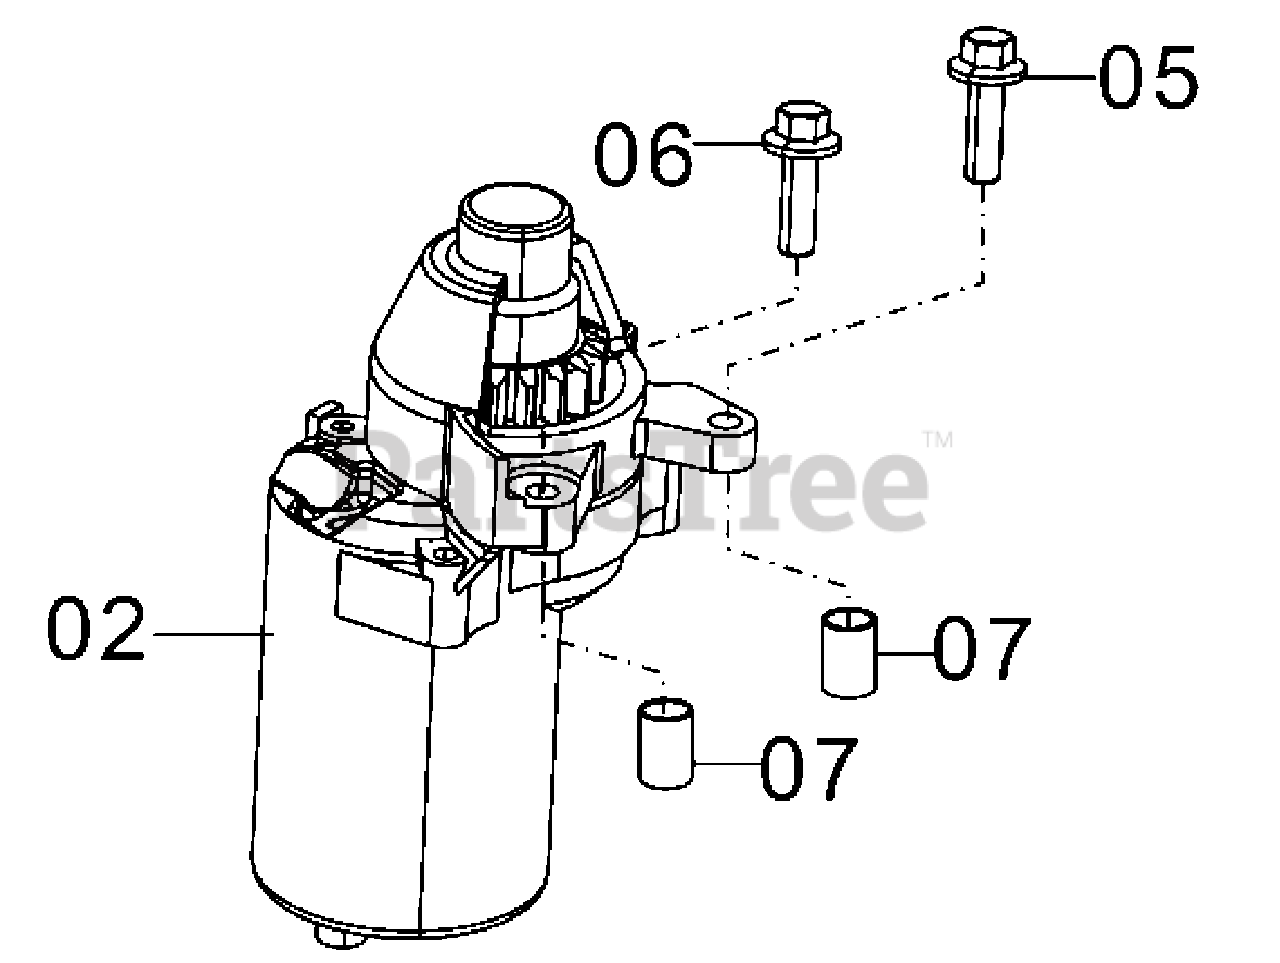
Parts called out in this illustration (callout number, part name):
710-02	STARTER MOTOR AY
710-05	BOLT, STARTER
710-06	BOLT, STARTER
